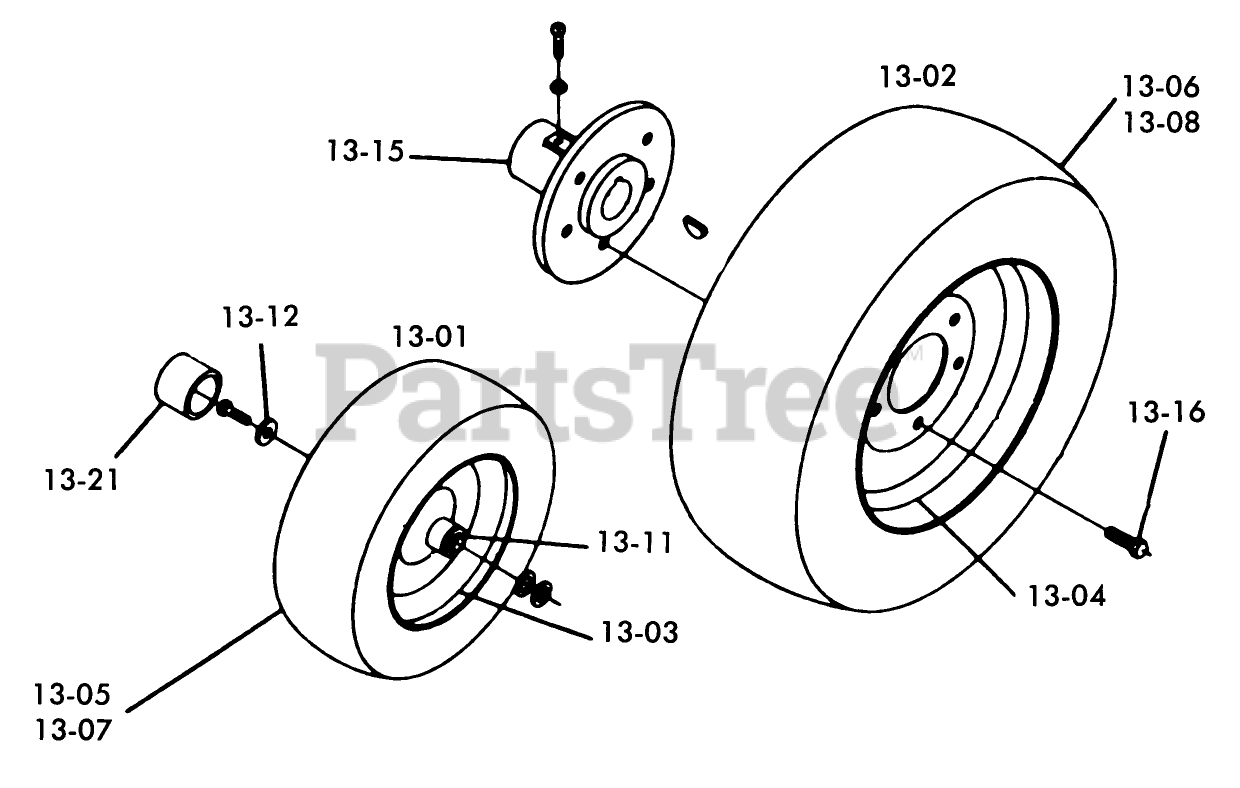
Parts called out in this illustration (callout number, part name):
13-04	VALVE
13-12	WASHER
13-12	WASHER-SHIM
13-15	KEY-WOODRUFF
